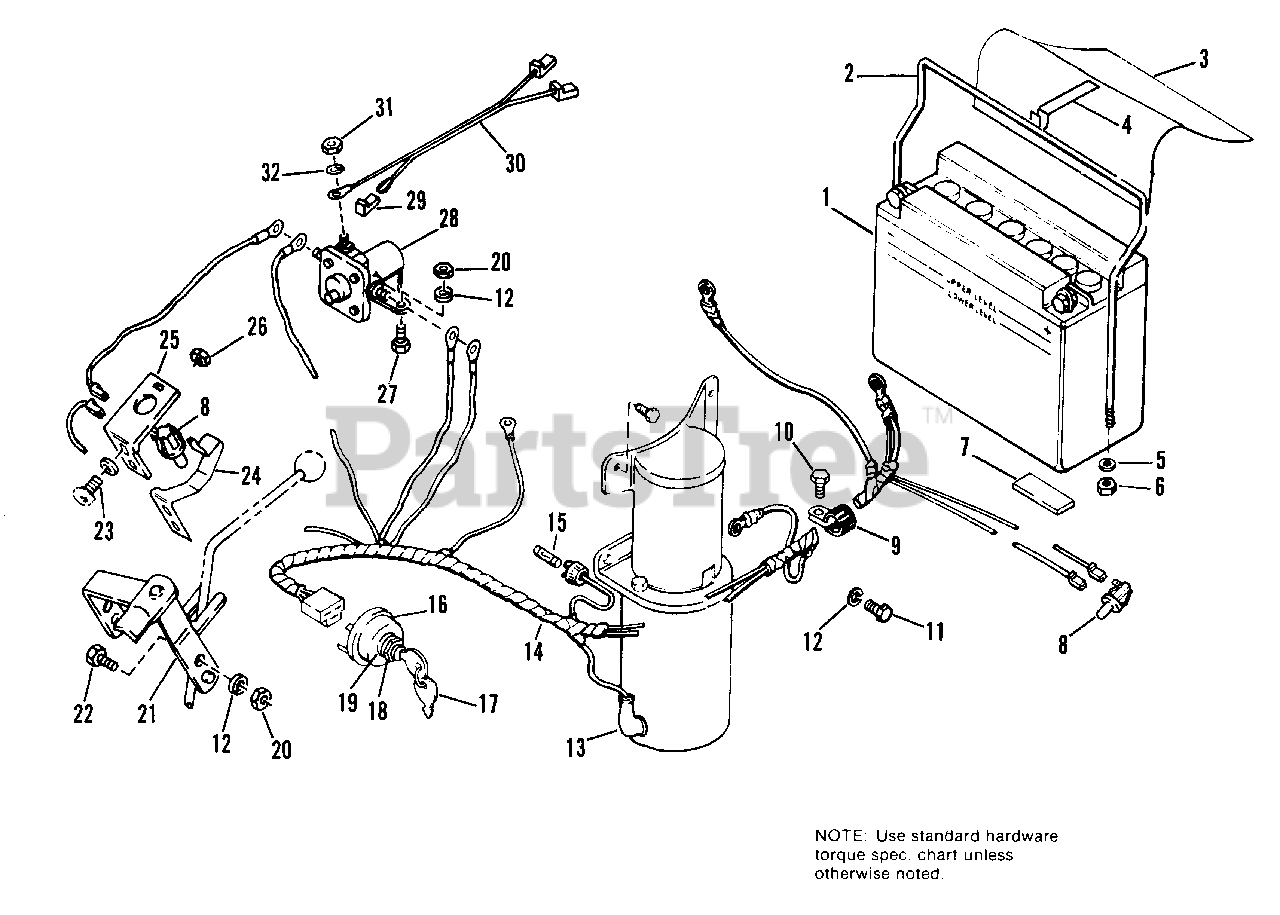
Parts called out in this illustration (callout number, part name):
2	CLAMP, Rod
3	INSULATION, Battery
5	LOCKWASHER, 1/4
6	NUT, Hex, Full, 1/4-20
7	GASKET, Felt
10	SCREW, Hex, Taptite, #10-24 x 1/2
11	CAPSCREW, Hex Hd., 5/16-18 x 5/8
12	LOCKWASHER, 5/16
13	COVER, Terminal
14	HARNESS ASSY
16	SWITCH, Starter W/Keys
18	NUT, Hex, Special
19	LOCKWASHER, Int., 9/16
20	NUT, Hex, Full, 5/16-18
21	PIVOT ASSY.
22	CAPSCREW, Hex Hd., 5/16-18 x 3/4
23	BOLT, Carriage, 1/4-20 x 3/4
24	CLIP, Spring
26	LOCKNUT, Flange, Hex, 1/4-20
27	SCREW, Hex, Taptite, 1/4-20 x 3/8
29	CONNECTOR, Insulated
31	LOCKWASHER, Ext., #10
32	NUT, Hex, Full, #10-32
